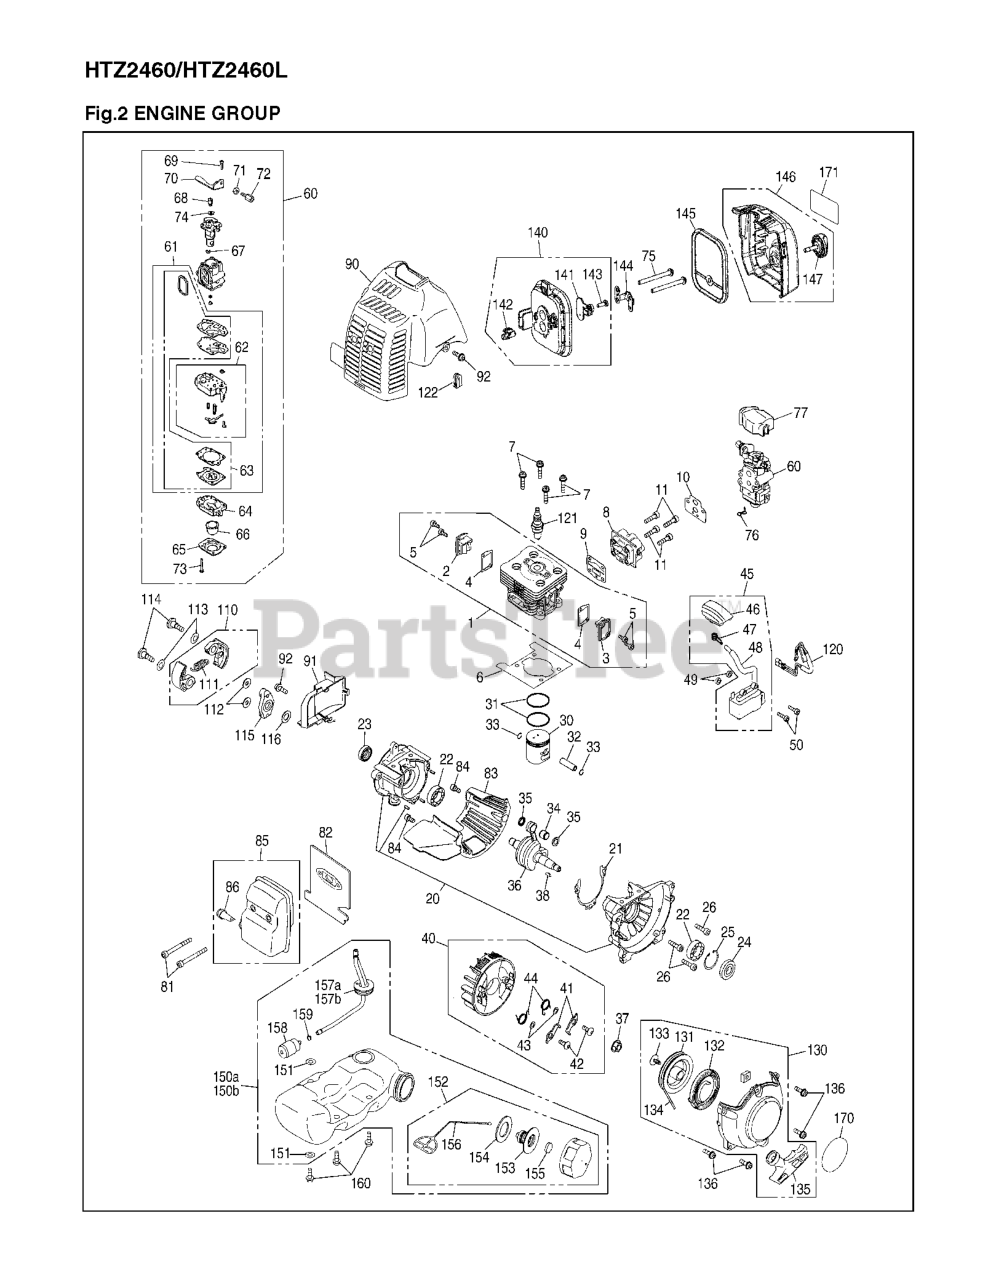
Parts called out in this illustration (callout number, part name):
1	CYLINDER COMPLETE
2	COVER, TR-S
3	COVER, TR-F
4	GASKET, TR
5	BOLT
6	GASKET, BASE
7	BOLT
8	INSULATOR
9	INSULATOR GASKET(R-848F0814B0)
10	GASKET, CARB
11	BOLT TORX
20	CRANKCASE COMP
21	GASKET, CASE
24	SEAL
32	PIN
36	CRANKSHAFT COMP
37	NUT
38	KEY
40	ROTOR ASSY
43	WASHER 5X10X10
45	COIL ASSY
49	SPACER
60	CARBURETOR ASSY.
61	REBUILD KIT
62	CARBURETOR BODY
63	GASKET KIT
65	1OVER
67	RING
68	SWIVEL
69	SCREW
70	BRACKET
72	ADJUSTER
74	WASHER
75	BOLT TORX
76	CLIP
86	ARRESTER
90	COVER,ENGINE
91	DEFLECTOR
110	SHOE COMP
115	PLATE CLUTCH
120	CORD COMP
121	PLUG CMR7H
130	RECOIL-A
133	SCREW
141	Choke Plate
142	Choke Lever
143	SCREW
145	ELEMENT
146	%CLEANER COVER ASSY
147	Cleaner Knob
150	TANK ASSY
153	HOLDER-A
157	PIPE COMP
158	FILTER ASSY
159	CLIP
170	LABEL RECOIL
